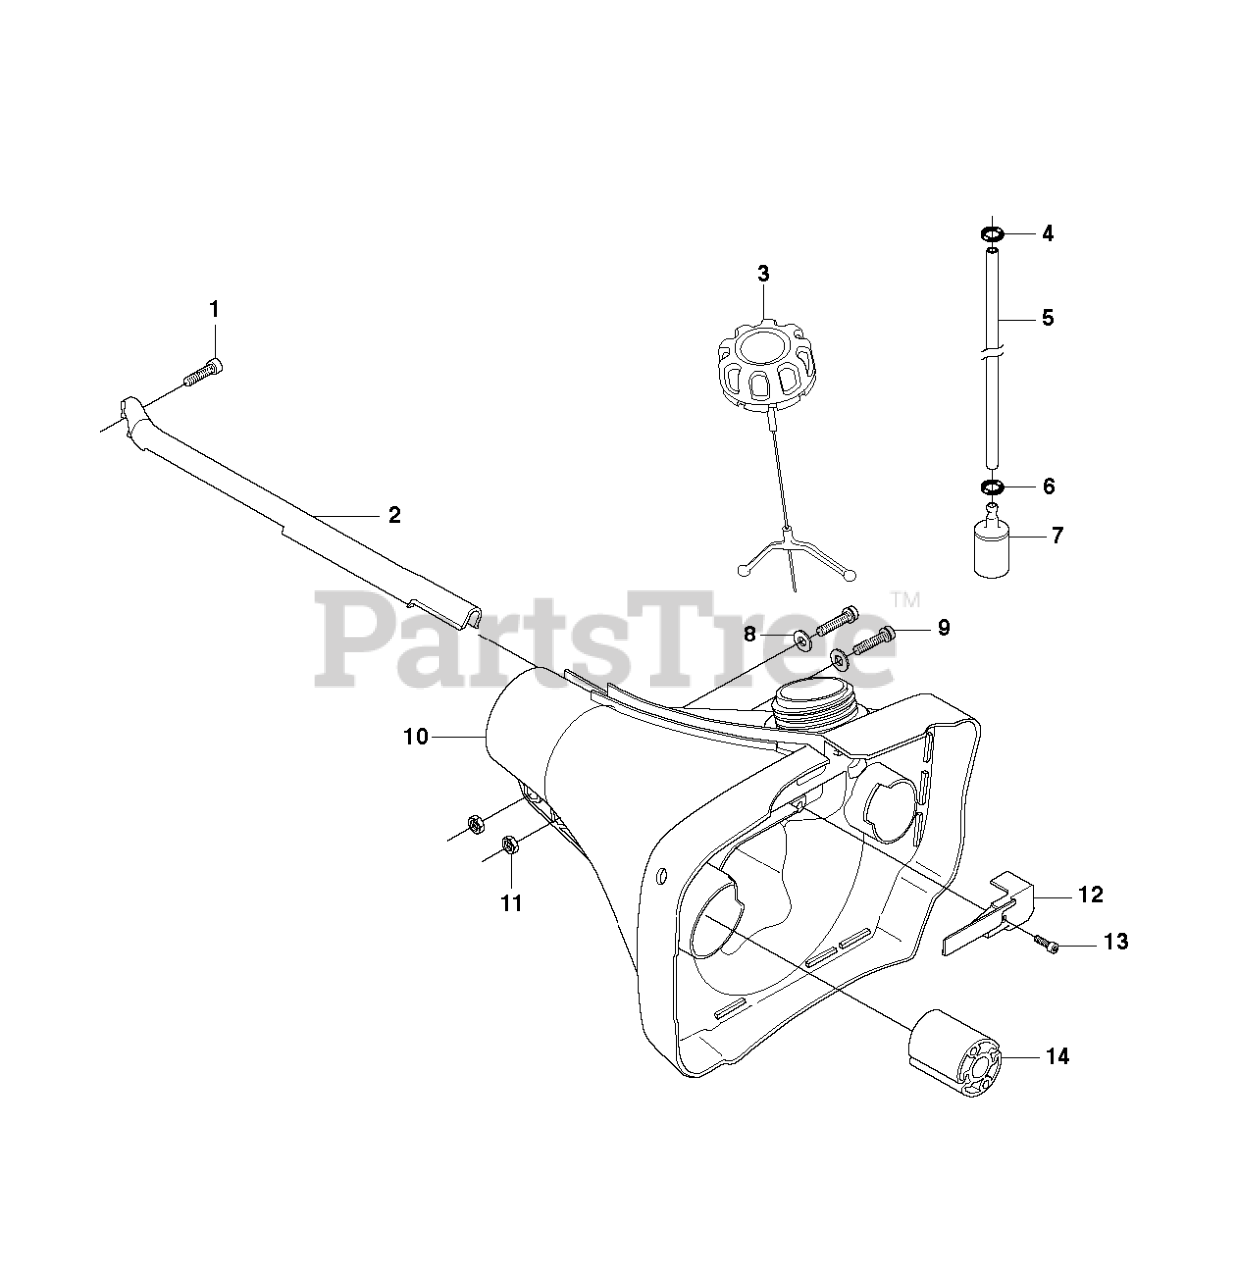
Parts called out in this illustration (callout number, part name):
2	PROTECTOR
3	%WINTER TANK CAP
5	FUEL HOSE
7	RP FUEL FILTER
8	WASHER 5.3X12
10	TANK UNIT
13	SCREW
14	ANTIVIBRATION ELEMENT
